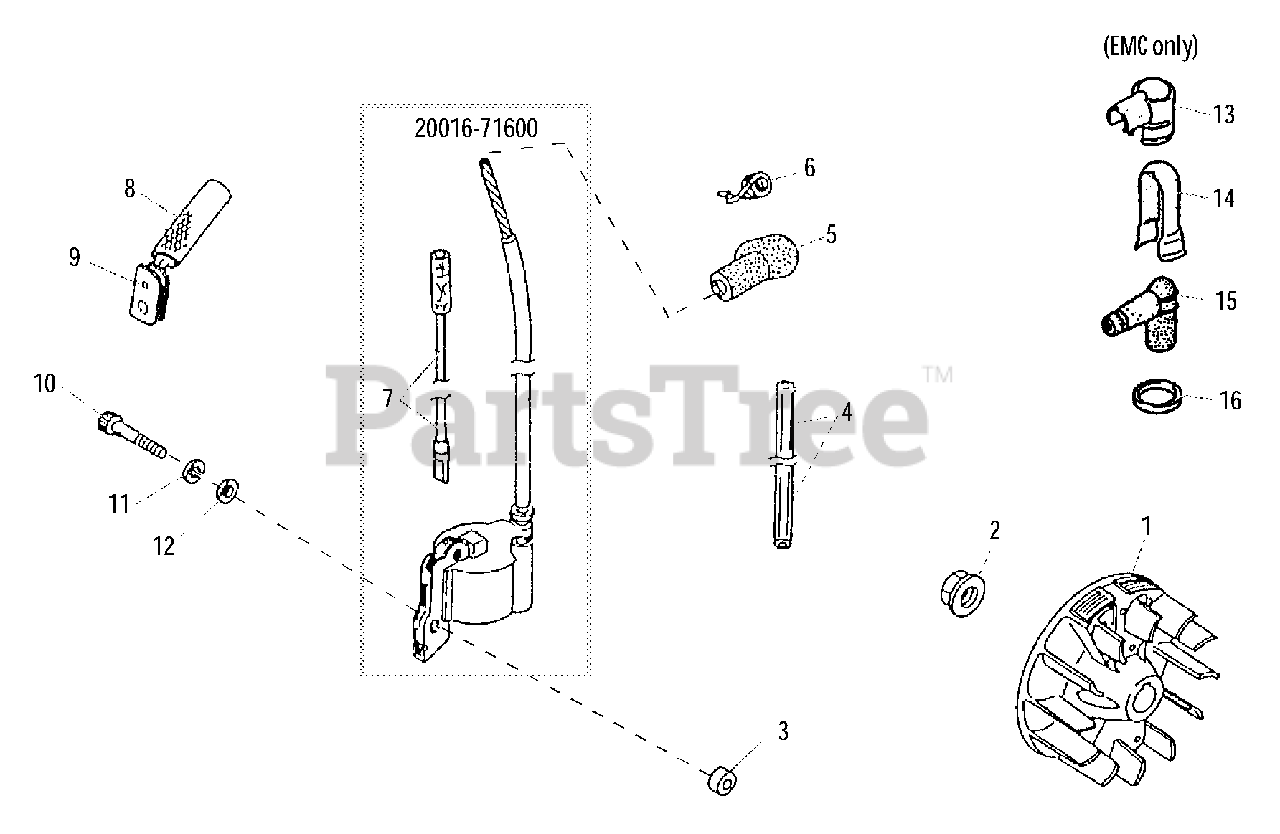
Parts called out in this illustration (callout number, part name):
1	FLYWHEEL
2	NUT M8
3	INSULATOR 4.2×11×6
4	TUBE, INSULATOR
5	CAP, SPARK PLUG
6	TERMINAL, SPARK PLUG
7	WIRE
8	TUBE, IGNITION COIL
9	GROMMET
10	BOLT
11	WASHER, SPRING 4 MM
12	WASHER 4 MM
13	COVER, CAP
14	SHIELD
15	CAP, SPARK PLUG
16	SEAL, SPARK PLUG
20016-71600	IGNITION COIL ASSY
